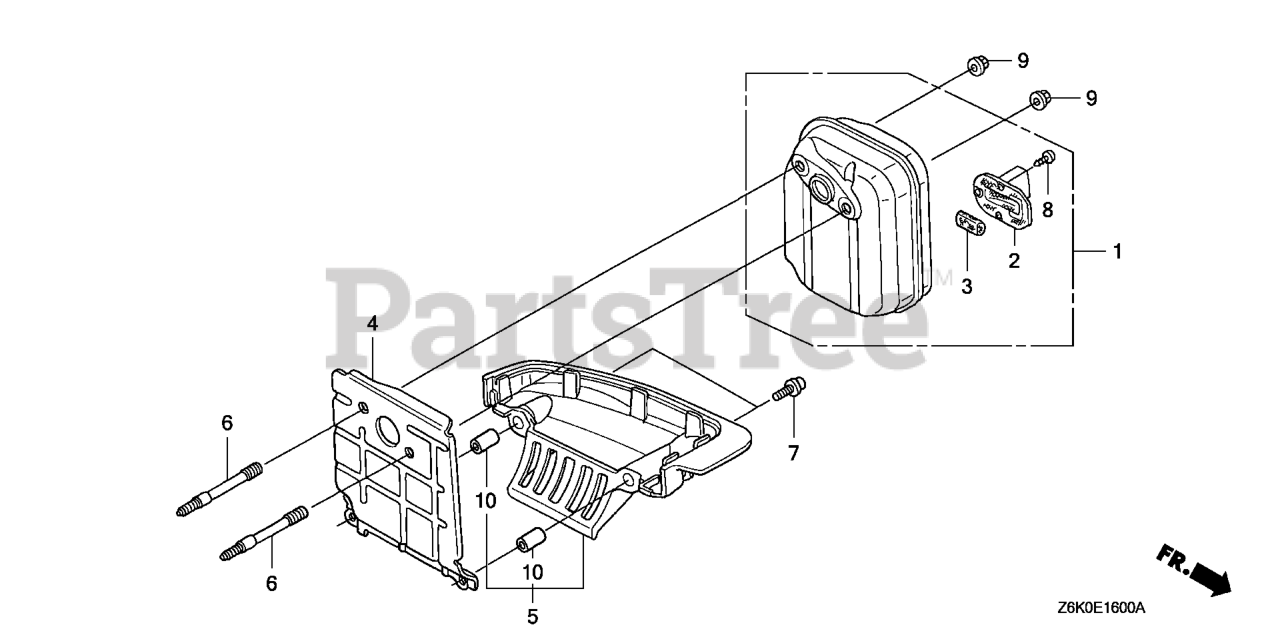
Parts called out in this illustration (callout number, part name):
1	MUFFLER (ARRESTER)
2	ARRESTER, SPARK
3	FILTER, EX.
4	GUIDE, AIR
5	GUIDE, AIR (LOWER)
6	BOLT, STUD (5X56.5)
7	BOLT, SOCKET (5X16)
8	SCREW, TAPPING (4X6) (TO INSTALL OPTIONAL SPARK ARRESTER)
9	NUT, SELF-LOCK (5MM)
10	COLLAR A, HEAD COVER
